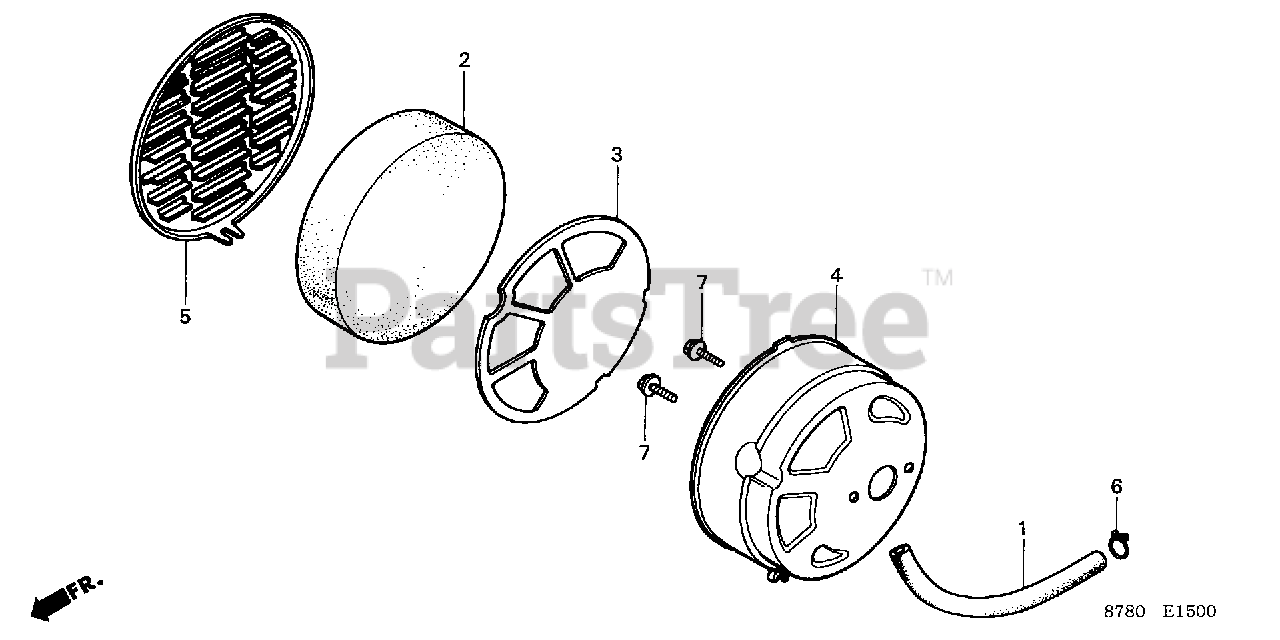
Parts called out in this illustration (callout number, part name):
1	TUBE, BREATHER (NOT AVAILABLE)
1	BULK HOSE, FUEL (8X1000) (8X125)
2	ELEMENT, AIR CLEANER
3	GRID, AIR CLEANER (NOT AVAILABLE)
4	HOUSING, AIR CLEANER
5	COVER, AIR CLEANER (NOT AVAILABLE)
6	CLIP, TUBE (B12.5)
7	BOLT, FLANGE (6X12)
